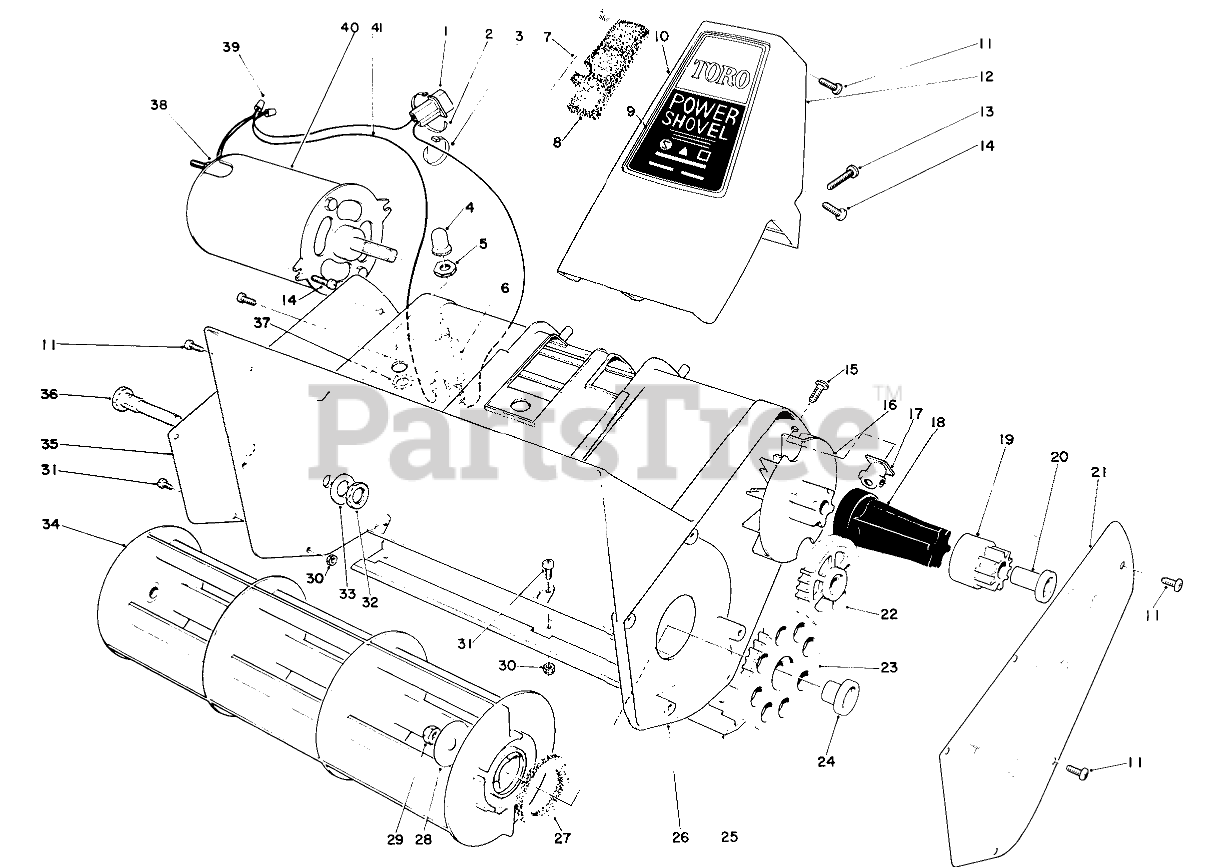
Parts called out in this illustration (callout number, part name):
1	HSG PIN CONNECTOR
2	TIE-CABLE
3	TIE-CABLE
4	Circuit Breaker Seal
5	Hex Nut
6	Circuit Breaker (Incl. Ref. #5)
7	RETAINER - FILTER
8	FOAM FILTER
9	DECAL-HDLE SUPRT (SEMKO
10	FRONT SUPPORT
11	SCREW-PPH
12	Handle Support-Back
13	SCREW-PPH
14	SCREW-PPH
15	SCREW-PPH
16	FAN, POWER SHOVEL
17	MOUNTING BLOCK
18	DRIVE COUPLING
19	Drive Gear (Incl. Ref. #20)
20	BUSHING, DRIVE GEAR
21	Gear Carrier
22	IDLER GEAR ASM
23	Rotor Gear (Incl. Ref. #24)
24	BUSHING, ROTOR GEAR
25	Scraper
26	HOUSING
27	FELT WASHER
28	ROTOR WASHER
29	NUT-LOCK, NI
30	NUT-LOCK
31	SCREW-PPH
32	NUT-LOCK, CONE
33	WASHER-FLAT
34	ROTOR
35	Cover-Right Side
36	ROTOR PIN
37	WASHER-LOCK/EXT
38	NUT-HEX
39	CONNECTOR WIRE JOINT
40	Motor
41	Wire Assembly
